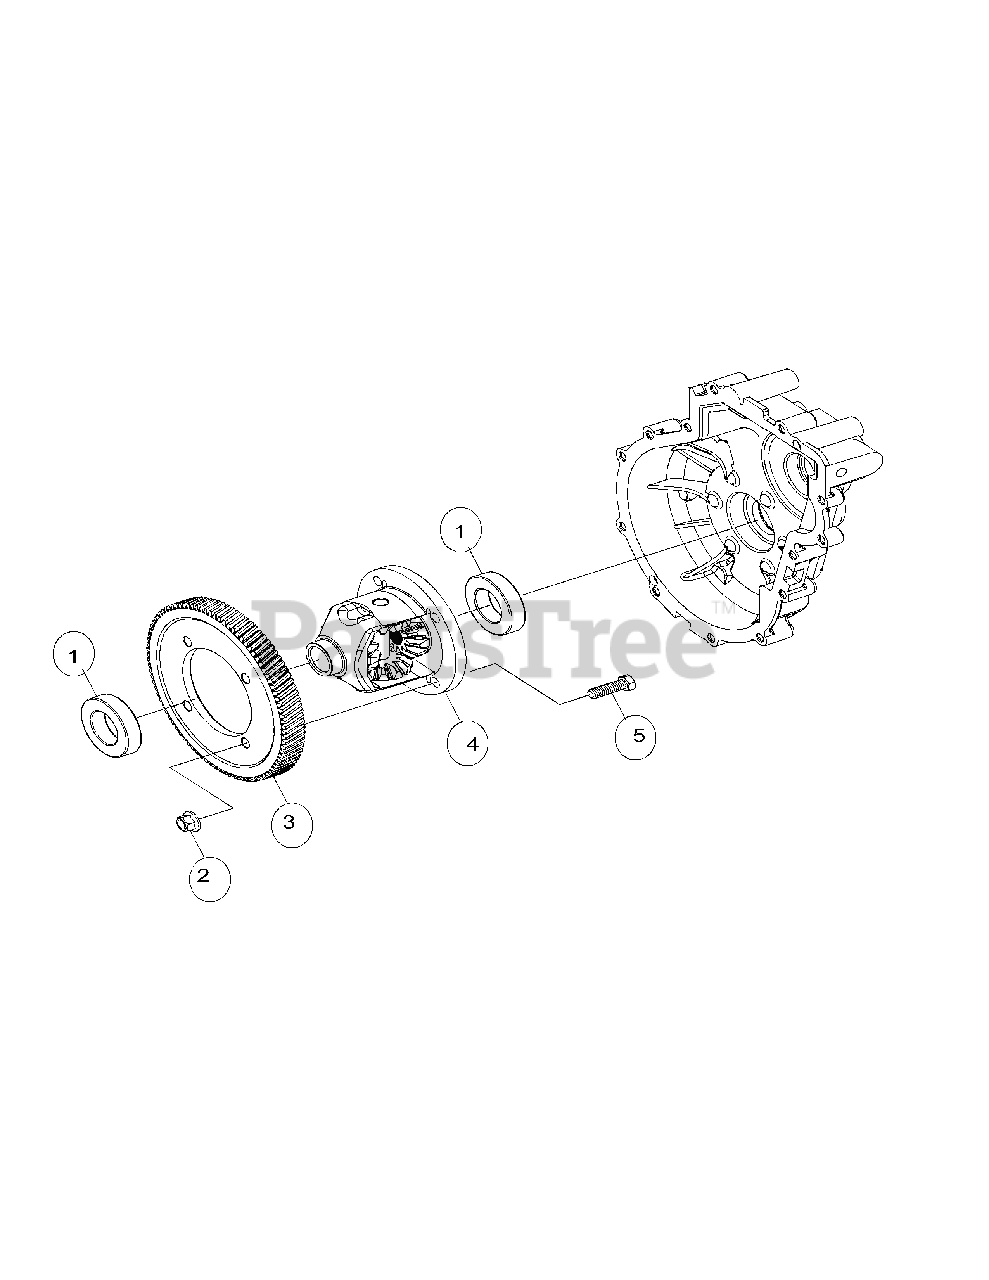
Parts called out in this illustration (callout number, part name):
1	Bearing, Ball
1	Ball Bearings Kit
3	Gear, Helical (Ring)
3	Internal Gears Kit
4	Assembly, Differential
